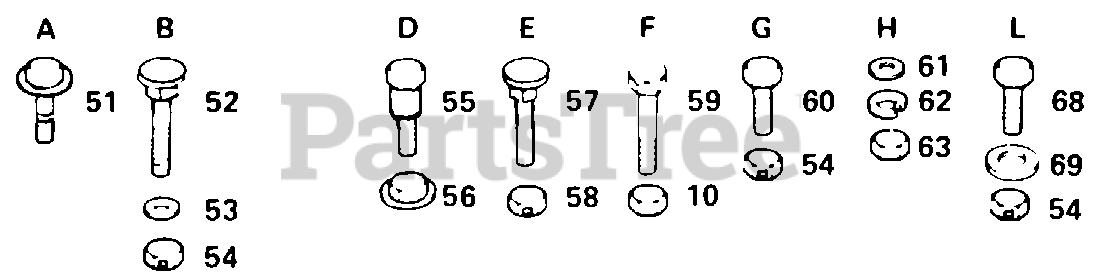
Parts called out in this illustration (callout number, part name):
51	SCREW LT
52	BOLT
53	WASHER
55	SHOULDER BOLT T
56	NUT T
57	BOLT
58	LOCKNUT
59	BOLT
60	BOLT
61	WASHER PM
68	BOLT
69	WASHER M
